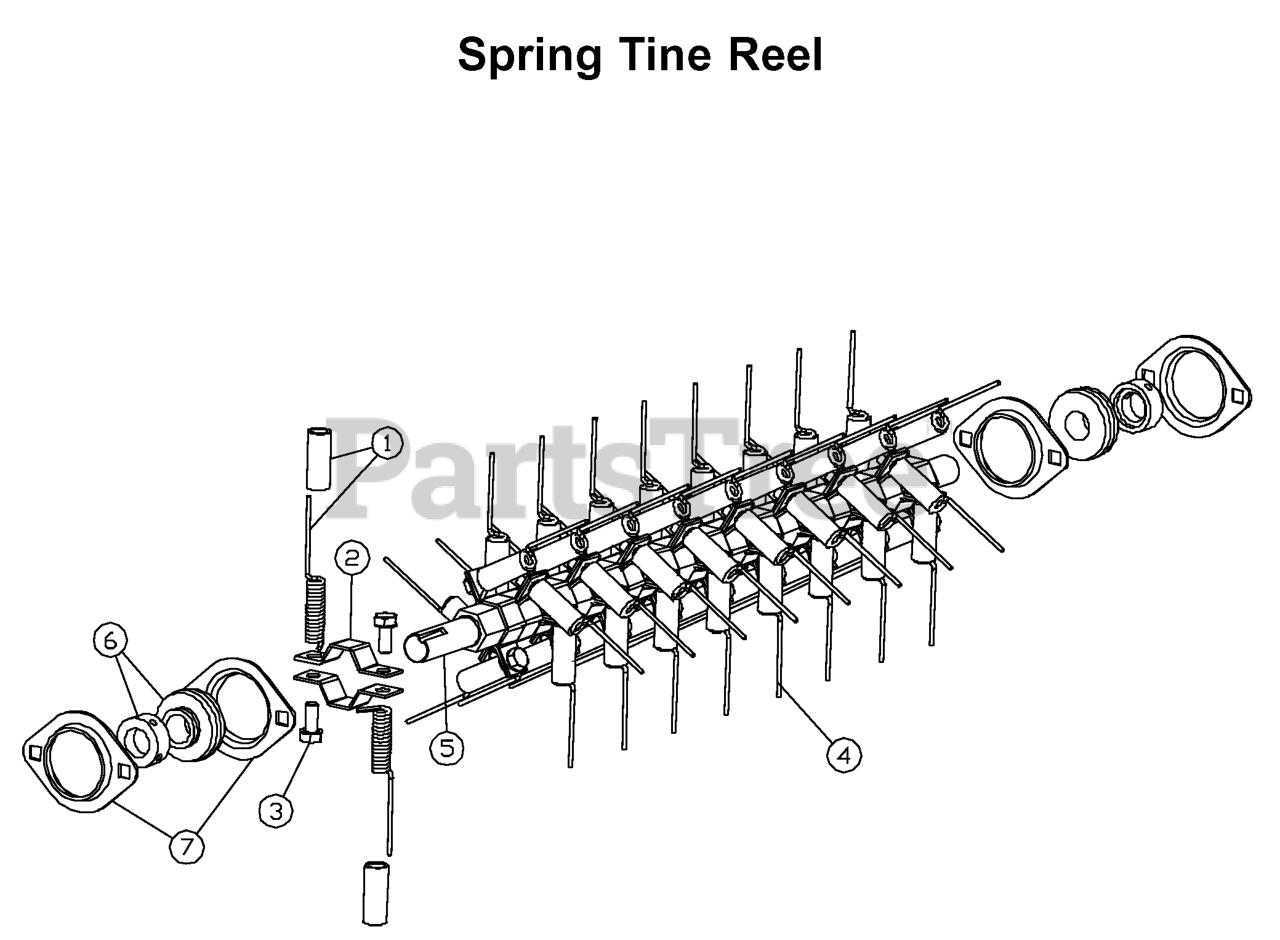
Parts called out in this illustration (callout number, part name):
1	SPRING TINE W/SLEEVE
2	CLAMP TINE PT# 491-011
4	TINE REEL ASSY
5	KIT, SHAFT TINE REEL
6	BEARING
7	STAMPING KIT
540054056	TINE REEL ASSY
